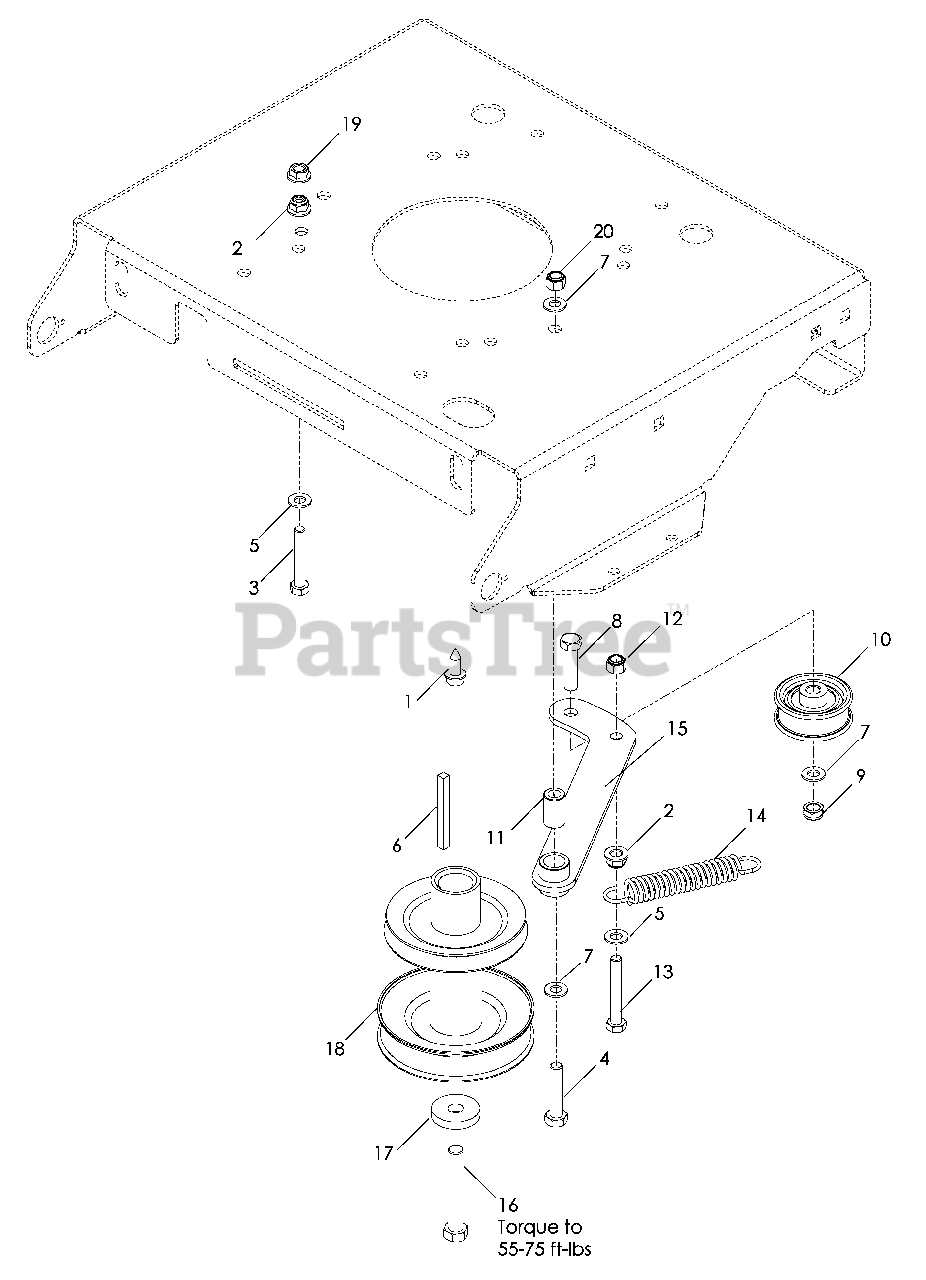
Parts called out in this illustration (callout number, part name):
1	HHFS 3/8-16 x 1 THD FRM
2	NUT 5/16-18 FLANGE NYLOC
3	HCS 5/16-18 x 2
4	HCS 3/8-16 x 1¾
5	WASHER 5/16 SAE FLAT
6	KEY ¼ SQ x 2½ LG
7	WASHER 3/8 FLAT STD
8	HCS 3/8-16 x 1½
9	NUT 3/8-16 HEX JAM NYLOC
10	PULLEY, IDLER
11	BUSHING, METAL
12	NUT 5/16-18 HEX NYLOC
13	HCS 5/16-18 x 2¼
14	SPRING 3½
15	IDLER
16	HCS 7/16-20 x 2¾
17	WASHER
18	PULLEY, ENGINE
19	NUT 5/16-18 HEX WHIZLK
20	NUT 3/8-16 HEX NYLOC
